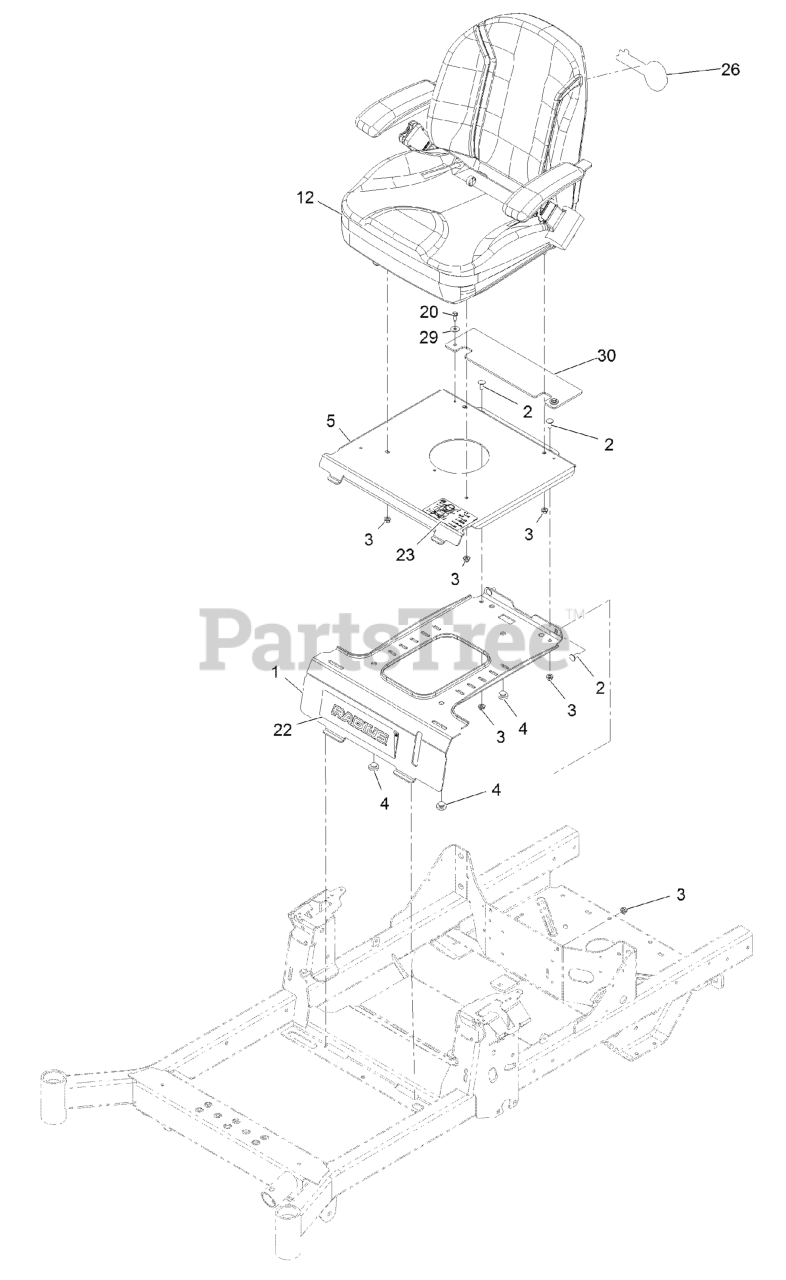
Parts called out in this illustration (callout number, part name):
1	PLATE-RETAINER, TANK
2	SCREW-CARR
3	NUT-HF, NI
4	BUMPER-SEAT
5	PLATE-SEAT, FIXED
12	ASM-SEAT EXMARK
20	SCREW-HWH, THREAD ROLL
22	DECAL-RADIUS LOGO
23	DECAL-AID, SERVICE
26	DECAL-EXMARK LOGO
30	GUARD, RUBBER
